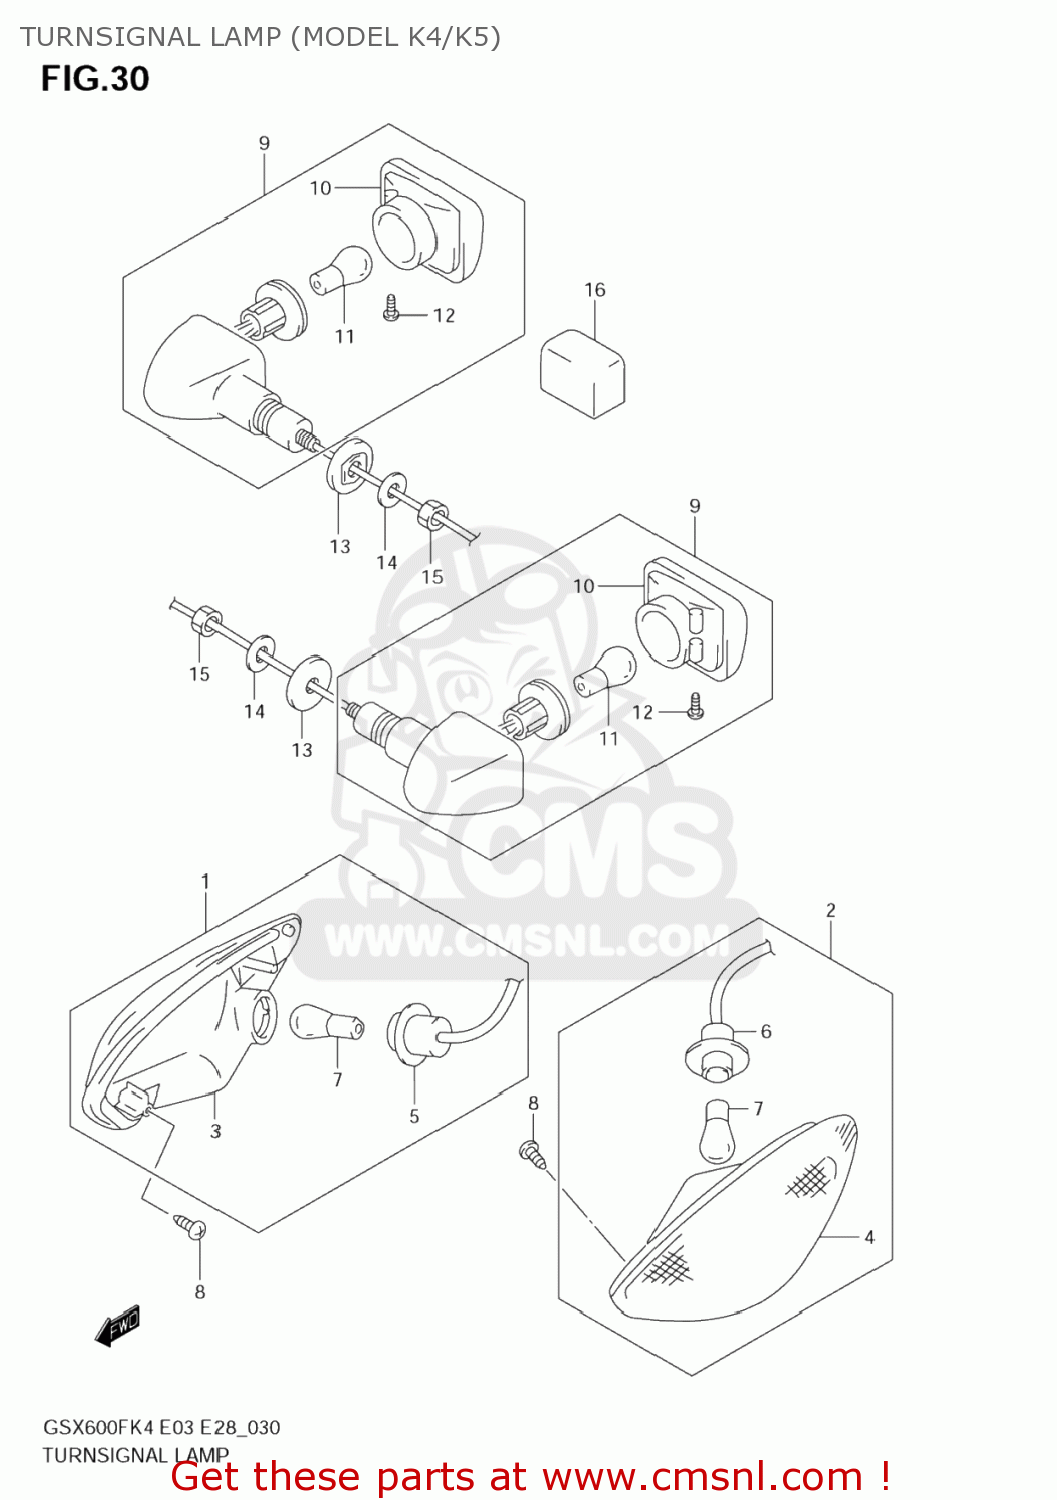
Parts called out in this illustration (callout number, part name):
1	LAMP ASSY,FR TURN SIGNAL,R
2	LAMP ASSY,FR TURN SIGNAL,L
3	LAMP UNIT,R
4	LAMP UNIT,L
5	SOCKET & CORD
6	SOCKET & CORD
7	BULB(12V21W)
8	SCREW
9	LAMP ASSY,RR TURNSIGNAL,R
10	LAMP UNIT
11	BULB(12V21W)
12	SCREW
13	SPACER,RR TURNSIGNAL
14	WASHER(10.5X30X2.3)
15	NUT
16	RELAY ASSY,TURNSIGNAL LAMP
